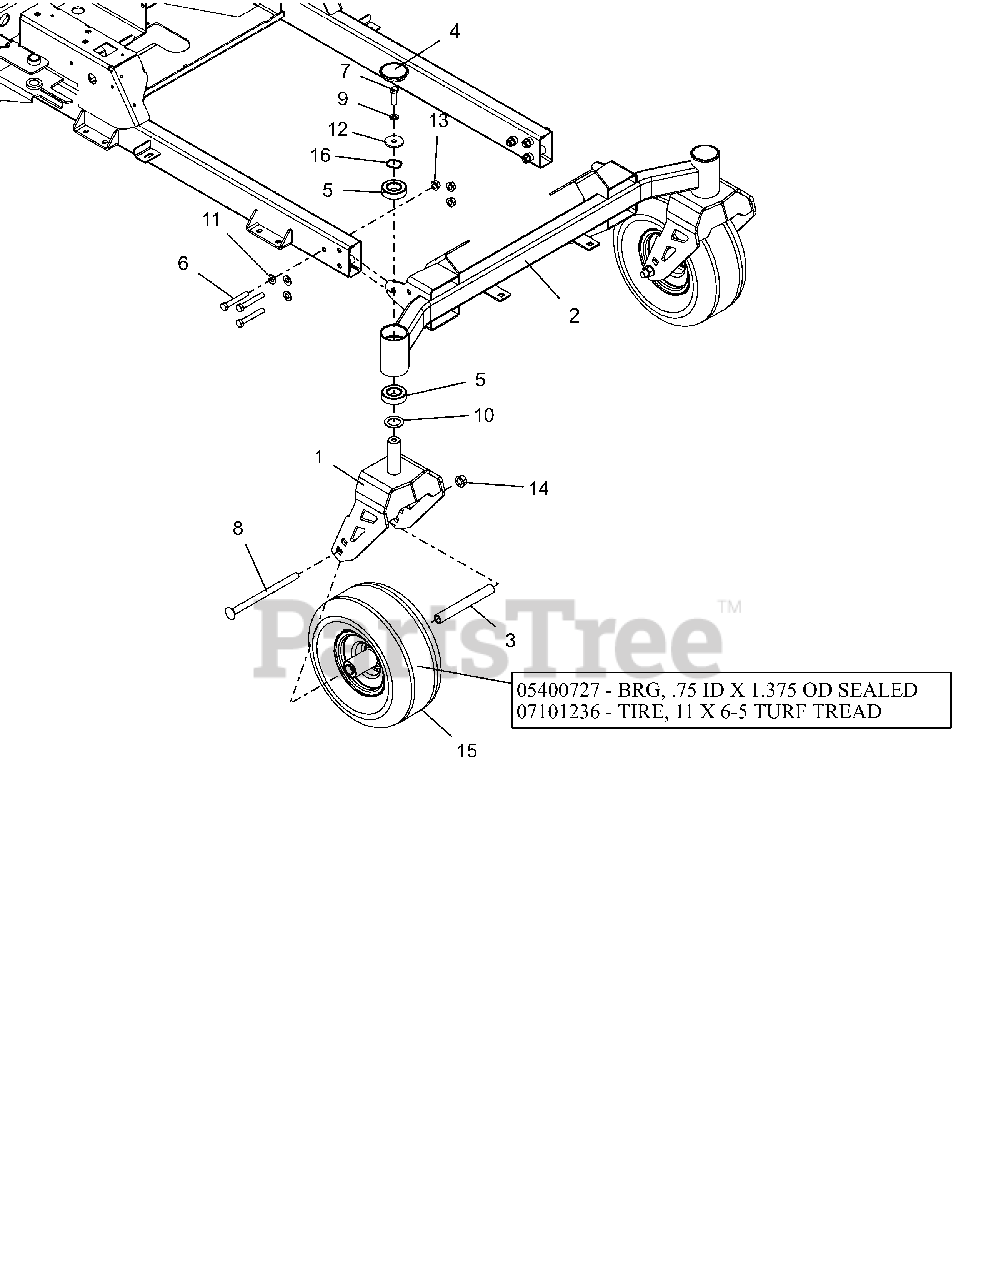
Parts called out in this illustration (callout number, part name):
1	WLDMT, CASTER FORK (WIDE)
2	WLDMT, AXLE FRONT
3	SPACER, FRONT WHEEL (WIDE 6.0)
4	CAP, DUST
5	BRG,BALL 1.00X2.00X.563(1641)
6	BLT-HEX .38-16X2.50 GR8 YWZC
7	@BLT-HEX .38-16X1.25 GR5 YWZC
8	@BLT-RDHDSQNK .50-13X7.50 G5YZ
9	@WSHR-LK .38X.094 REG YWZC
10	WSHR-HRD-THRS 1.007X1.542X.062
11	WSHR-HDND .406X.812X.055
12	WSHR-FL-STL .380X1.50X.125YWZC
13	NUT-LK-TOP-FLG .38-16 GRG YWZC
14	@NUT-LK-TOP-FLG .50-13 YWZC
15	TIRE/WHEEL ASSY, 11X6-5
15	BRG, .75 ID X 1.375 OD SEALED
15	TIRE, 11X6-5 TURF TREAD
16	WSHR-WAVE 1.0X1.25X.028 .145FH
